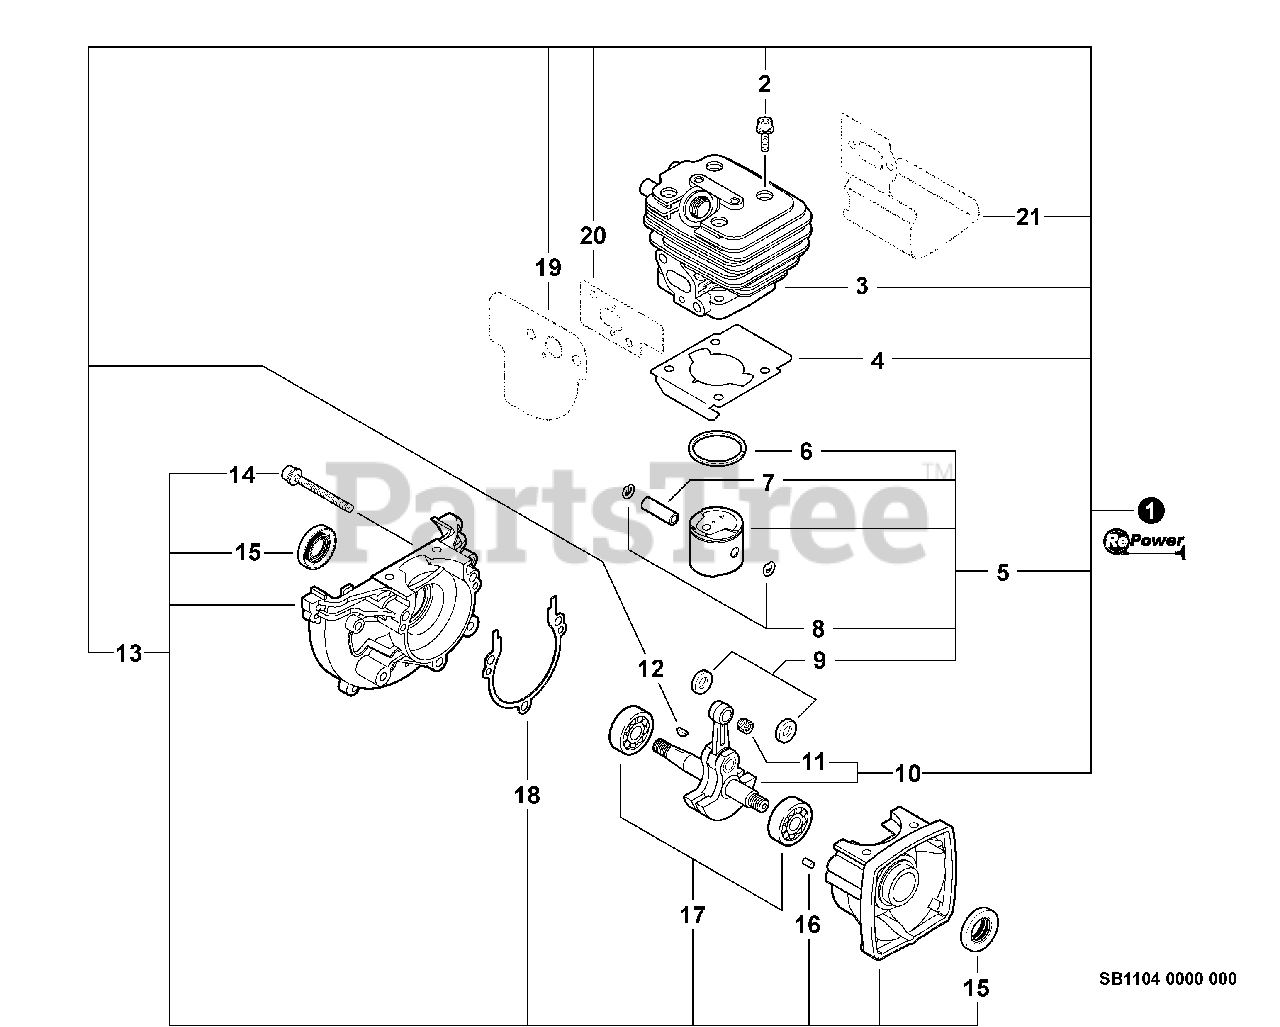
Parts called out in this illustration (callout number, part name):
1	SHORT BLOCK
2	BOLT 5×25
3	CYLINDER
4	GASKET, CYLINDER
5	PISTON KIT
6	RING, PISTON
7	PIN, PISTON
8	RING, SNAP
9	WASHER, THRUST
10	CRANKSHAFT ASSY
11	BEARING, NEEDLE 8
12	KEY, WOODRUFF
13	CRANKCASE KIT
14	BOLT 5×28
15	SEAL, OIL 12
16	PIN, LOCATING 4×8
17	BEARING, BALL - 6201 C3
18	GASKET, CRANKCASE
19	GASKET, INTAKE
20	GASKET, INTAKE
21	SHIELD, EXHAUST
